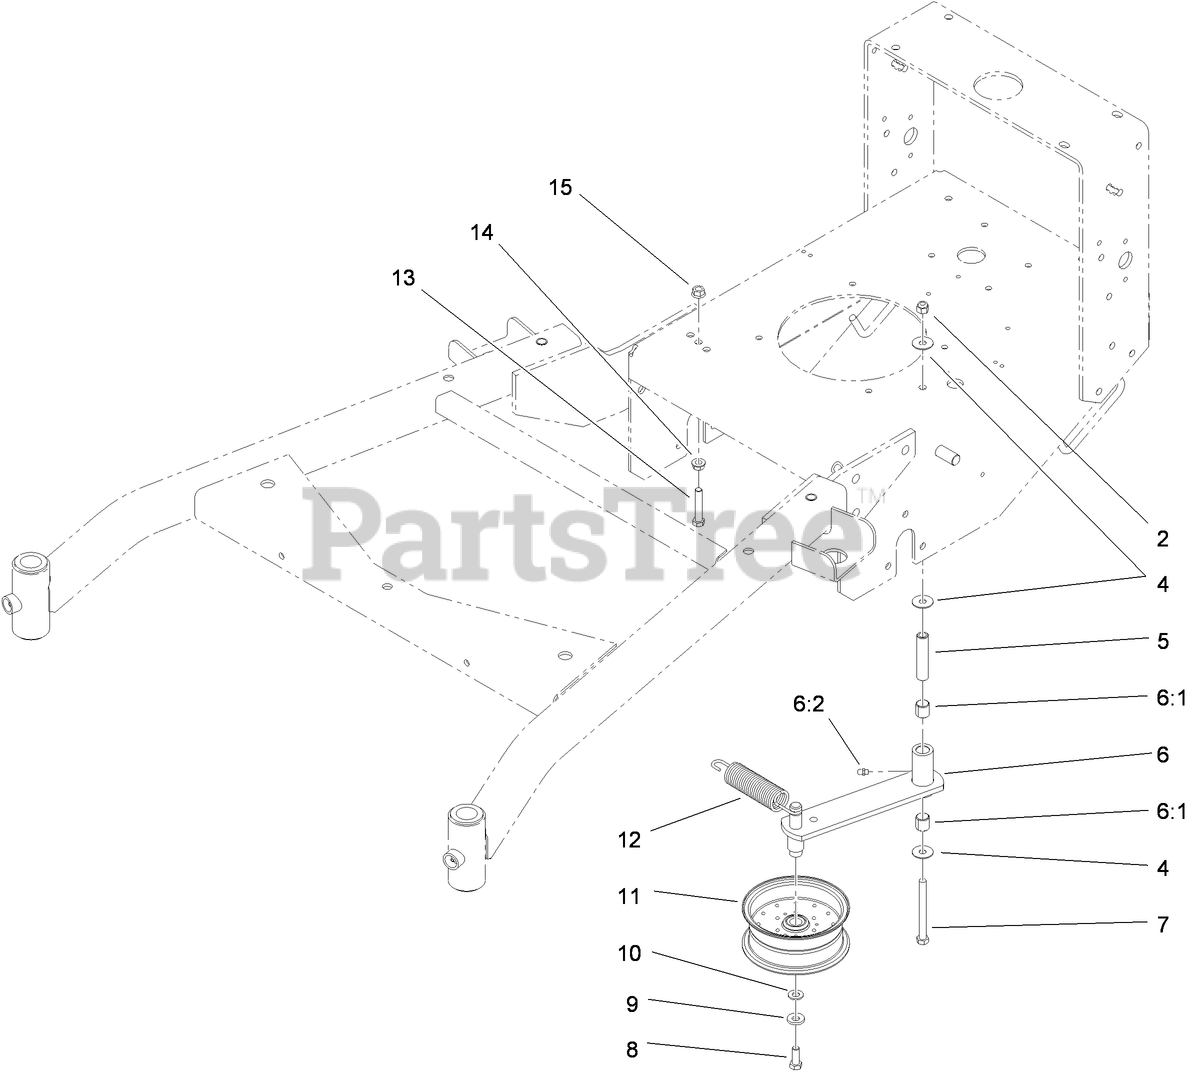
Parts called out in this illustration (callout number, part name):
2	NUT-LOCK, NI
4	WASHER
5	TUBE-IDLER
6	IDLER ARM ASM
6:1	SLEEVE-BEARING
6:2	FITTING-GREASE
7	SCREW-HH
8	SCREW-HH
9	WASHER-BELLEVILLE
10	WASHER-FLAT
11	PULLEY-IDLER
12	SPRING-EXTENSION
13	SCREW-HH
14	NUT-HHF, WHIZ
15	NUT-HF
